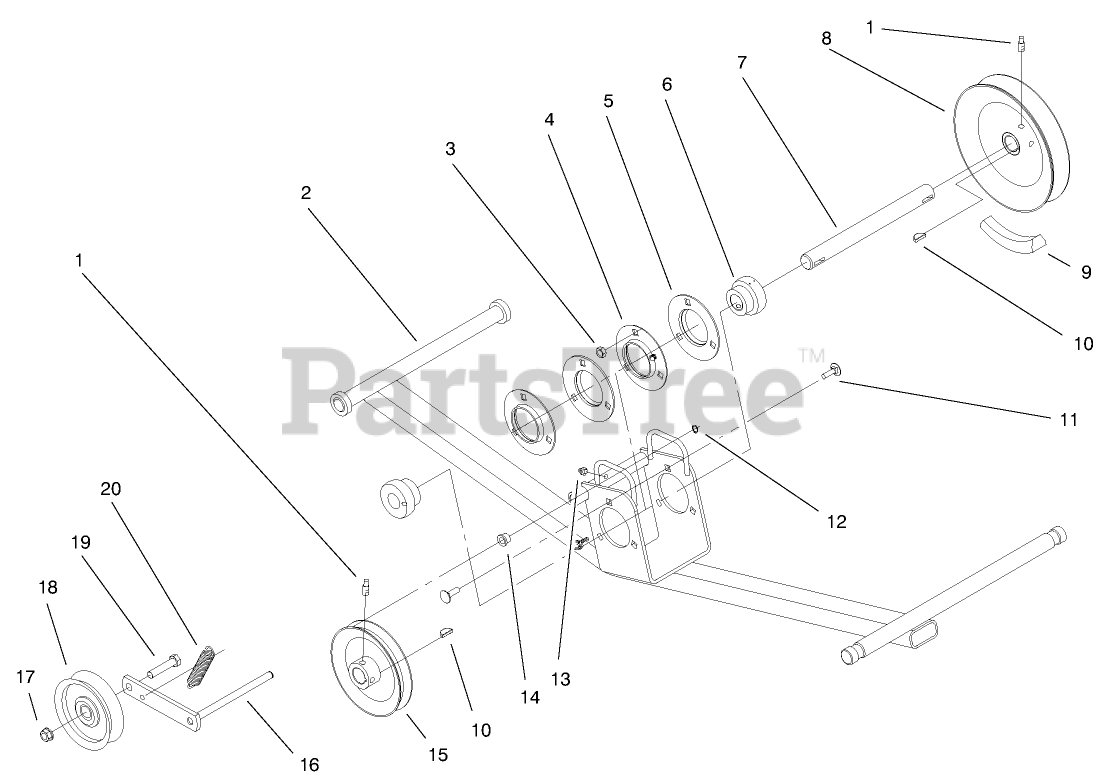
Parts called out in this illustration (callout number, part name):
1	SCREW-SQH
1	PIN-CLEVIS
2	PIN-HAIR
3	NUT-LOCK, NI
4	FLANGE-ZERK RELUBE
5	FLANGE
6	BEARING AND COLLAR
7	SHAFT-JACK
8	PULLEY-DRIVE
9	V-BELT-FRONT
10	KEY-WOODRUFF
11	BOLT-CARR
12	RING-RETAINING
13	FITTING-GREASE
14	BUSHING-FLANGED
14	GUIDE-CABLE
15	PULLEY-V
17	NUT-LOCK, NI
18	PULLEY-IDLER, FLAT
19	SCREW-HH
20	SPRING-BRAKE
